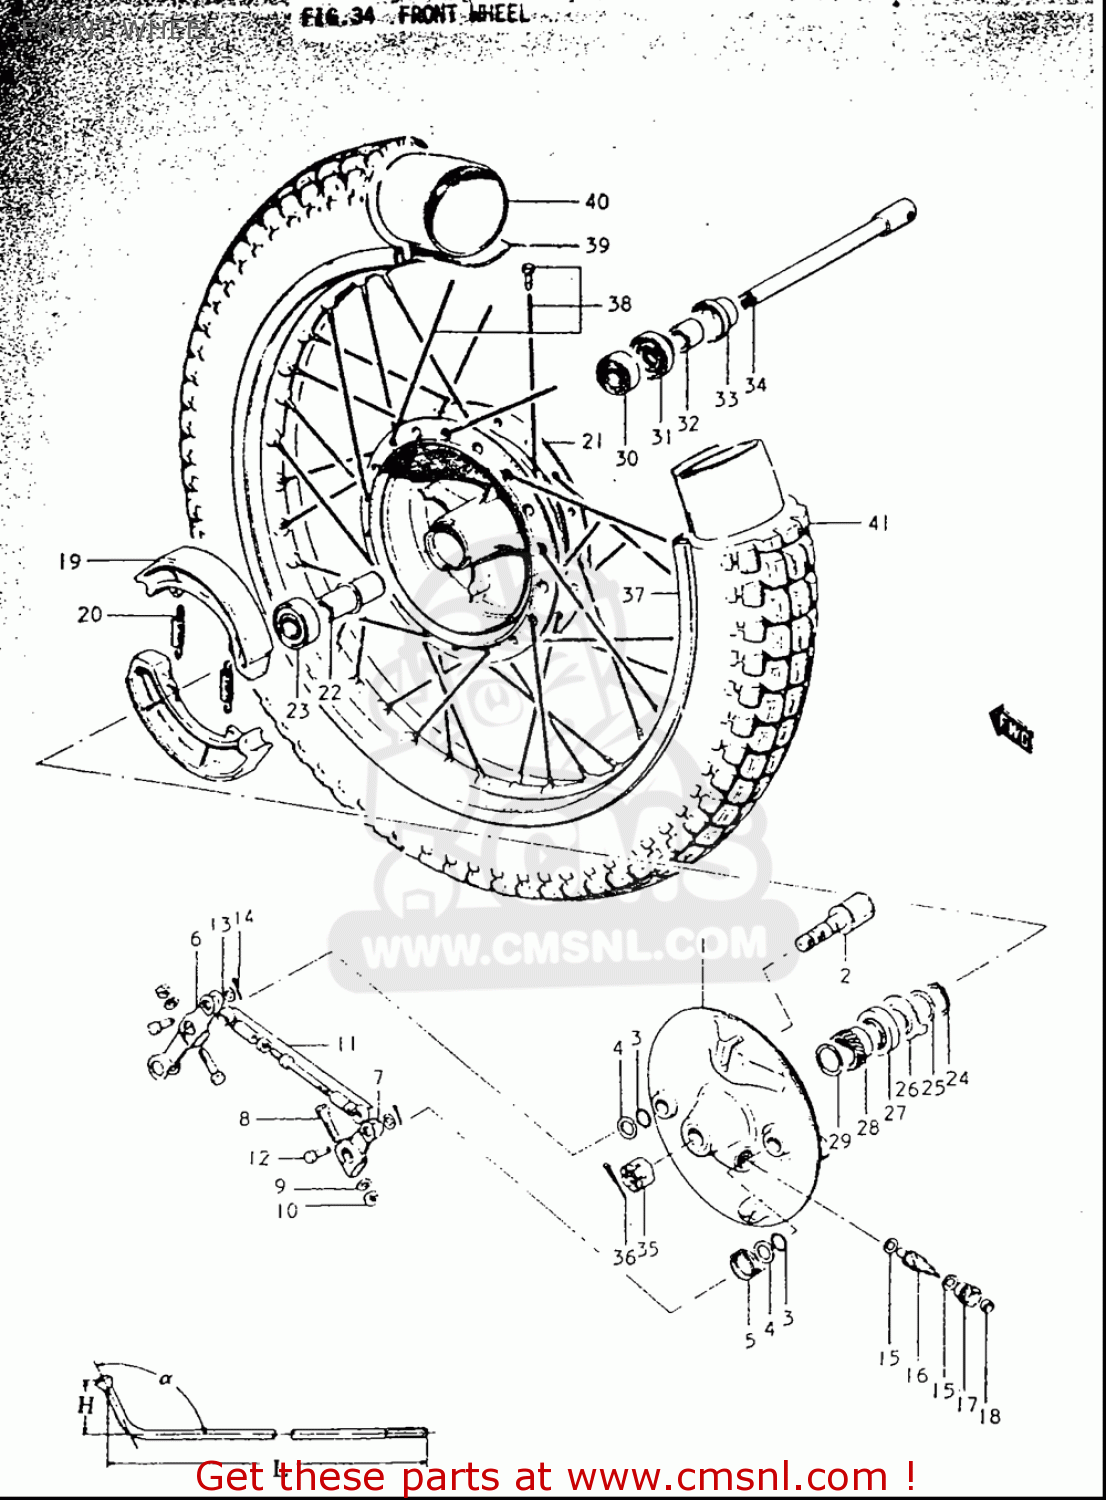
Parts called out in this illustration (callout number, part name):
3	O RING(D:2.4,ID:14.8)
4	WASHER(15.5X24X1.6)
5	SPRING
8	BOLT(6X31)
9	WASHER
10	NUT
13	WASHER
14	PIN 12X10
15	WASHER(5.1X9X0.4)
16	PINION,SPEEDOMETER
17	BUSHING,SPEEDOMETER PINION
18	SEAL,OIL(6X10X3)
19	SHOE,BRAKE
23	BEARING
24	CIRCLIP
25	WASHER(22.5X27X1)
26	DRIVER,SPEEDOMETER GEAR
27	SEAL,OIL(26X38X4)
29	WASHER(22.5X27X1)
30	BEARING
32	SPACER
35	NUT
37	RIM,WHEEL
39	PROTECTOR,WHL INR TUBE
40	TUBE ASSEMBLY,WHEEL,INNER
